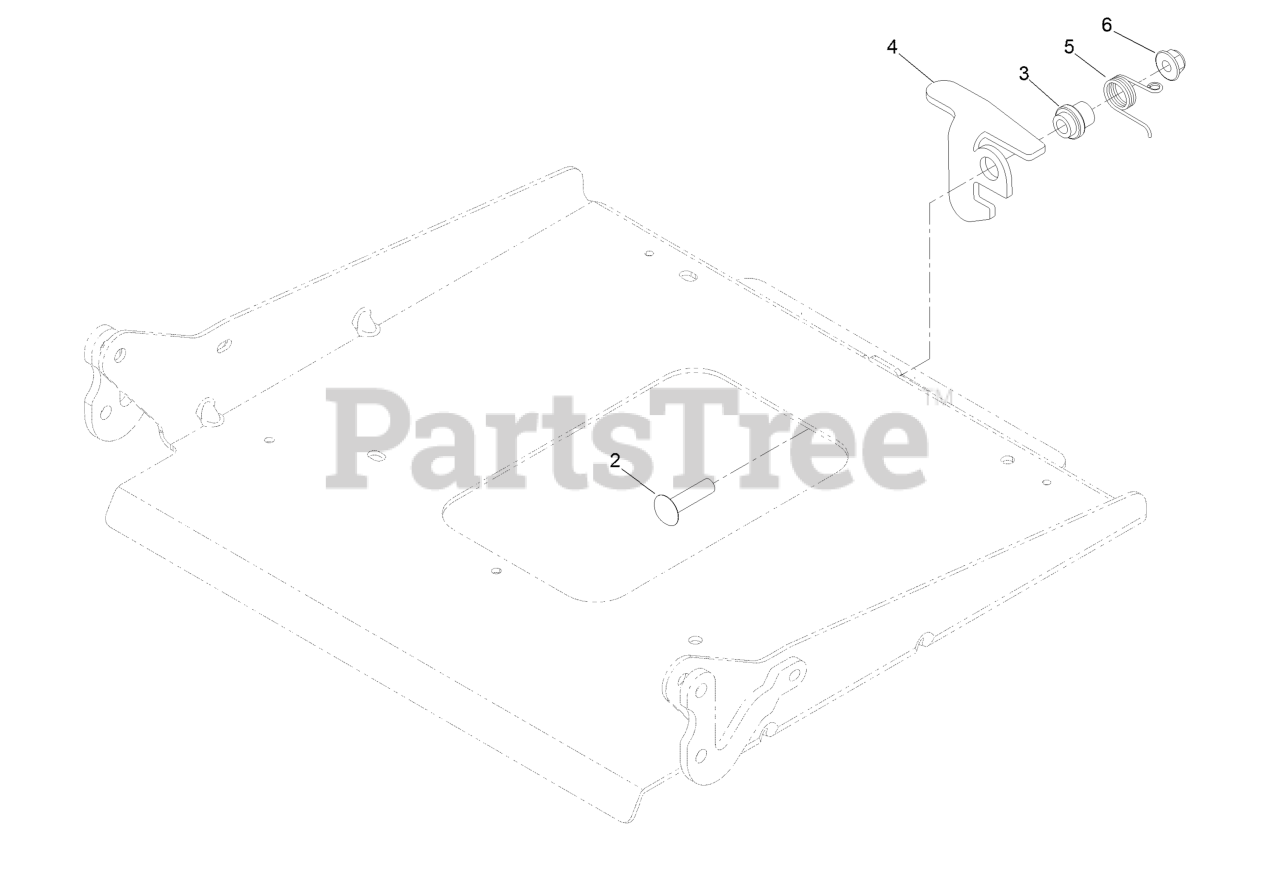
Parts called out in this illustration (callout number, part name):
2	Screw-CARR
3	Bushing-Latch, Seat
4	Latch-Catch, Single
5	Spring-Torsion, Latch
6	Nut-HF, NI
